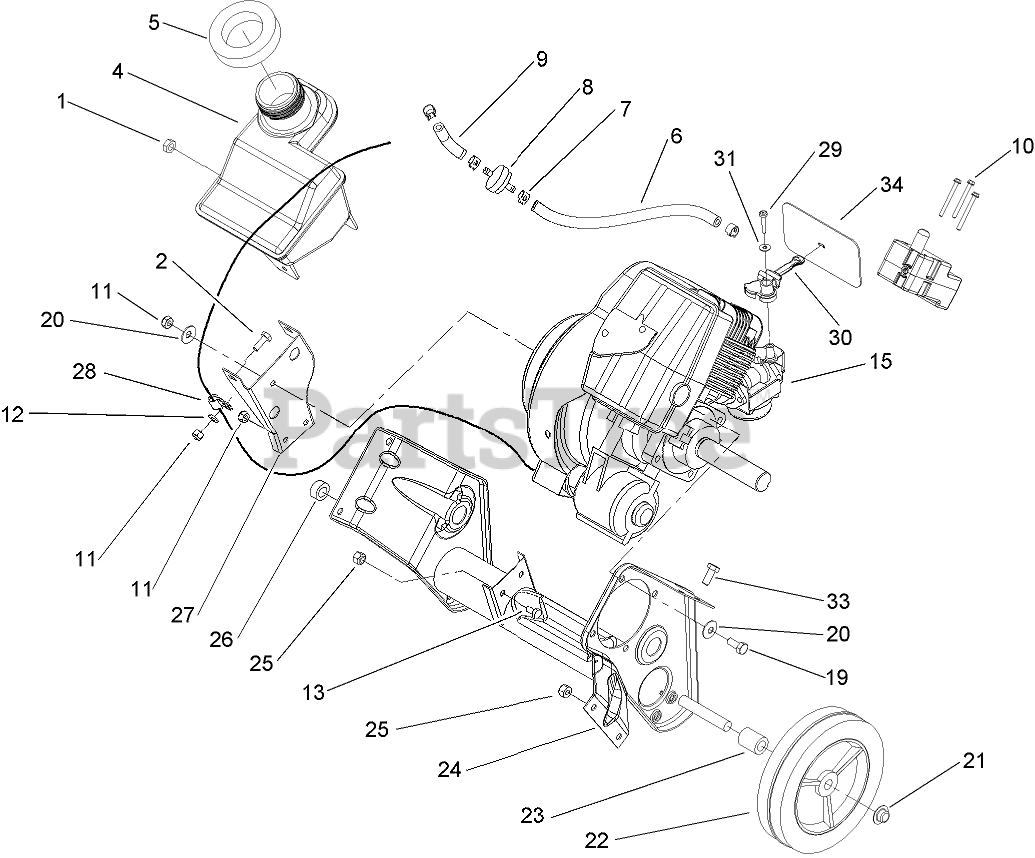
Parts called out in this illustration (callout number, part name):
1	NUT-LOCK, CONE
2	SCREW-HH
4	Tank-Gas
5	SEAL-FOAM
6	LINE-FUEL
7	CLAMP-HOSE
8	FILTER-FUEL
9	HOSE-FUEL
10	SCREW-PLASTITE
11	NUT-LOCK, NI
12	WASHER-FLAT
13	SCREW-HH
19	SCREW-HH
20	WASHER-BELLEVILLE
21	NUT-PUSH
22	WHEEL
23	SPACER-WHEEL
25	NUT-LOCK, NI
26	SPACER-WHEEL
27	BRACKET-SUPPORT, RECOIL
28	CLAMP
29	SCREW-PPH, PLASTITE
30	LEVER-CHOKE
31	WASHER-FLAT
33	SCREW-HH
34	SHIELD-HOLE, CHOKE
